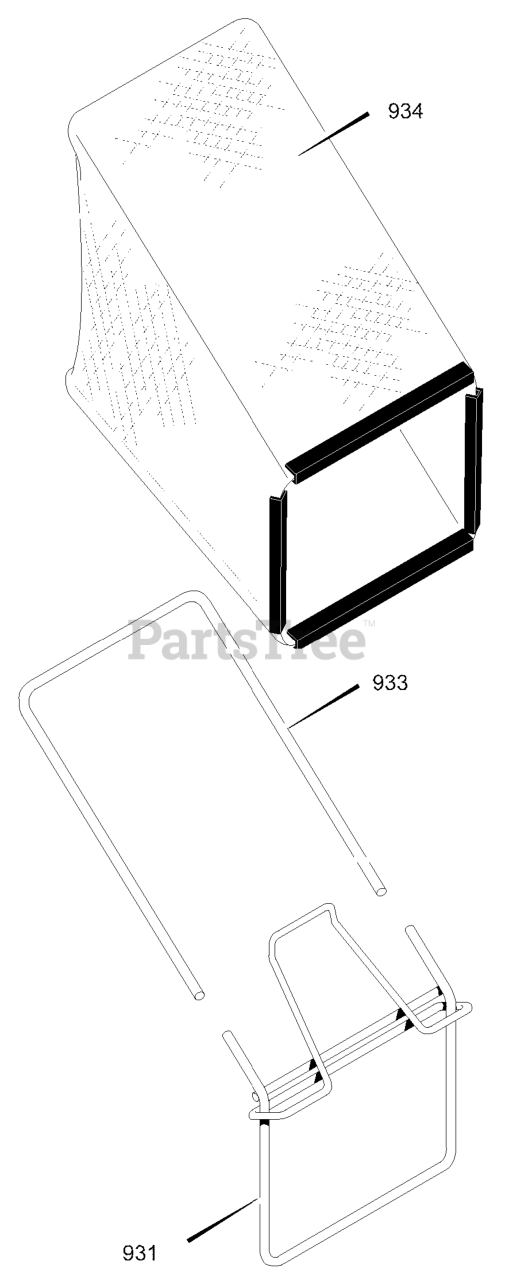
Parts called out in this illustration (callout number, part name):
931	Bag, Frame Assy.
933	Frame, Catcher Bag
934	Bag, Catcher
